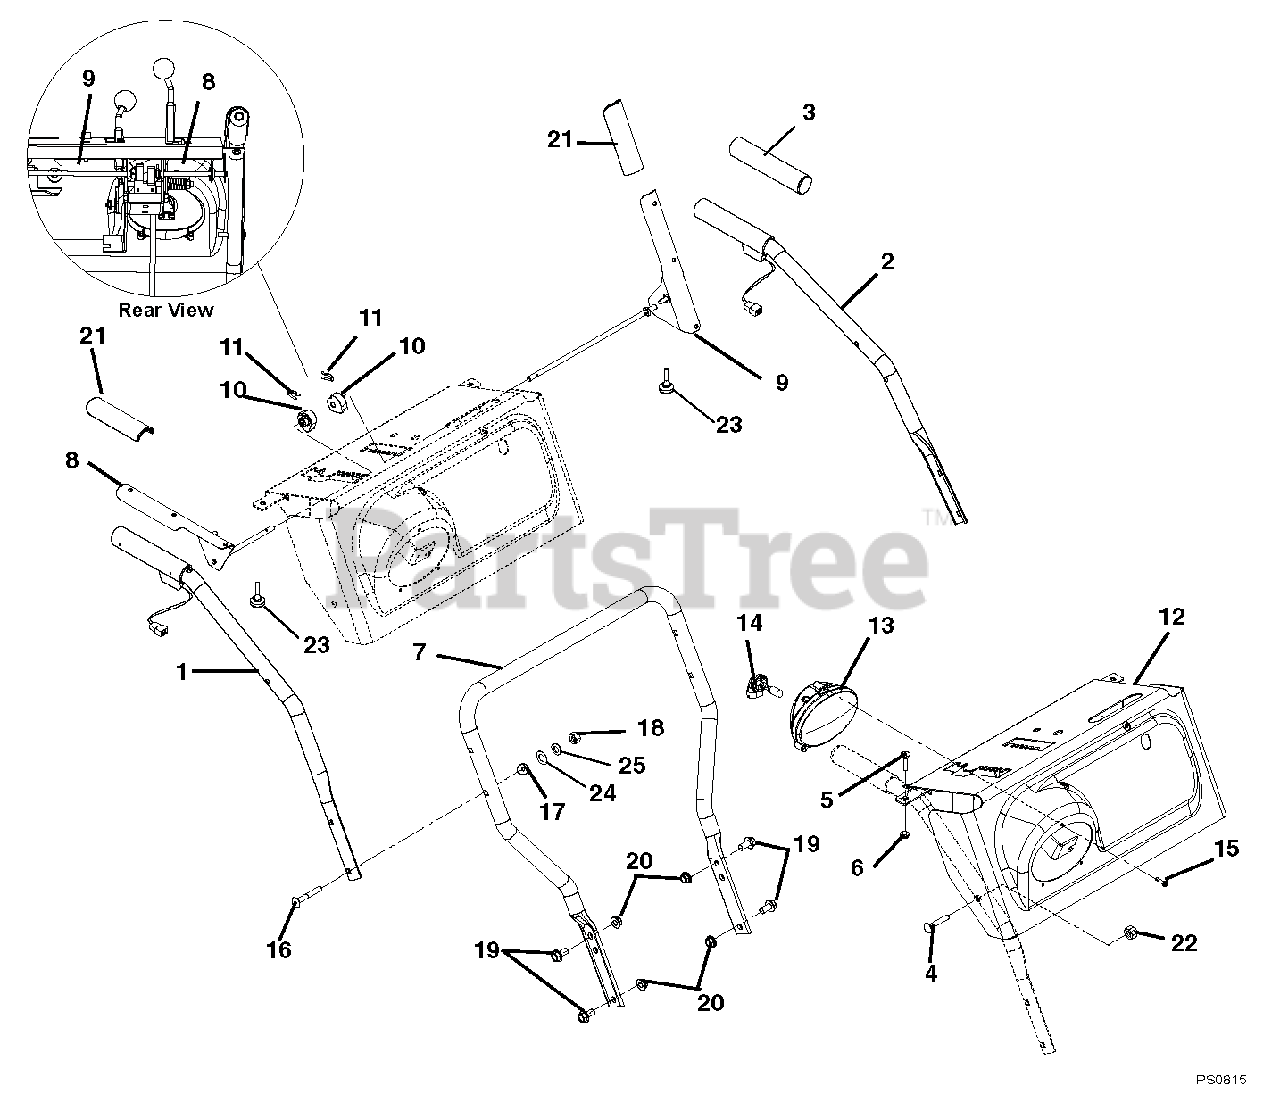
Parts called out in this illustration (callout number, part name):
1	HANDLEBAR, UPPER RH-W/HW
1	HANDLEBAR, UPPER-RH
2	HANDLEBAR, UPPER LH-W/HW
2	HANDLEBAR, UPPER-LH
3	HANDLE GRIP
4	@BLT-RDHDSQNK .31-18X1.75 G5YZ
5	BLT-RDHDXLSQNK.25-20X1.25 G5ZC
6	@NUT-LK-TOP-FLG .25-20 YWZC
7	HANDLEBAR, LOWER
8	LEVER, RH-ATTACHMENT
9	LEVER, LH-TRACTION
10	CAM, INTERLOCK
11	PIN, SPRING CLIP
12	PANEL-W/CONTROL HW DECAL
12	PANEL-W/CONTROL DECAL
13	LIGHT, HALOGEN ASSY.
14	BULB, LIGHT-HALOGEN 20W
15	SCR-TAP 10-16X.75 HI-LO PPH
16	@BLT-RDHDSQNK .31-18X2.25 G5YZ
17	SPACER, HANDLEBAR
18	@NUT-LK-NYL .312-18 YWZC
19	BLT-SERHFWH .38-16X.75 YWZC
20	@NUT-LK-TOP-FLG .38-16 YWZC
21	GRIP, CLUTCH LEVER, LH AND RH
22	@NUT-LK-CTR .31-18 YWZC
23	BUMPER, RUBBER - PULL MOUNT
24	@WSHR-FL-STL.38X.875X.083 YWZC
25	@WSHR-LK .31X.078 REG YWZC
